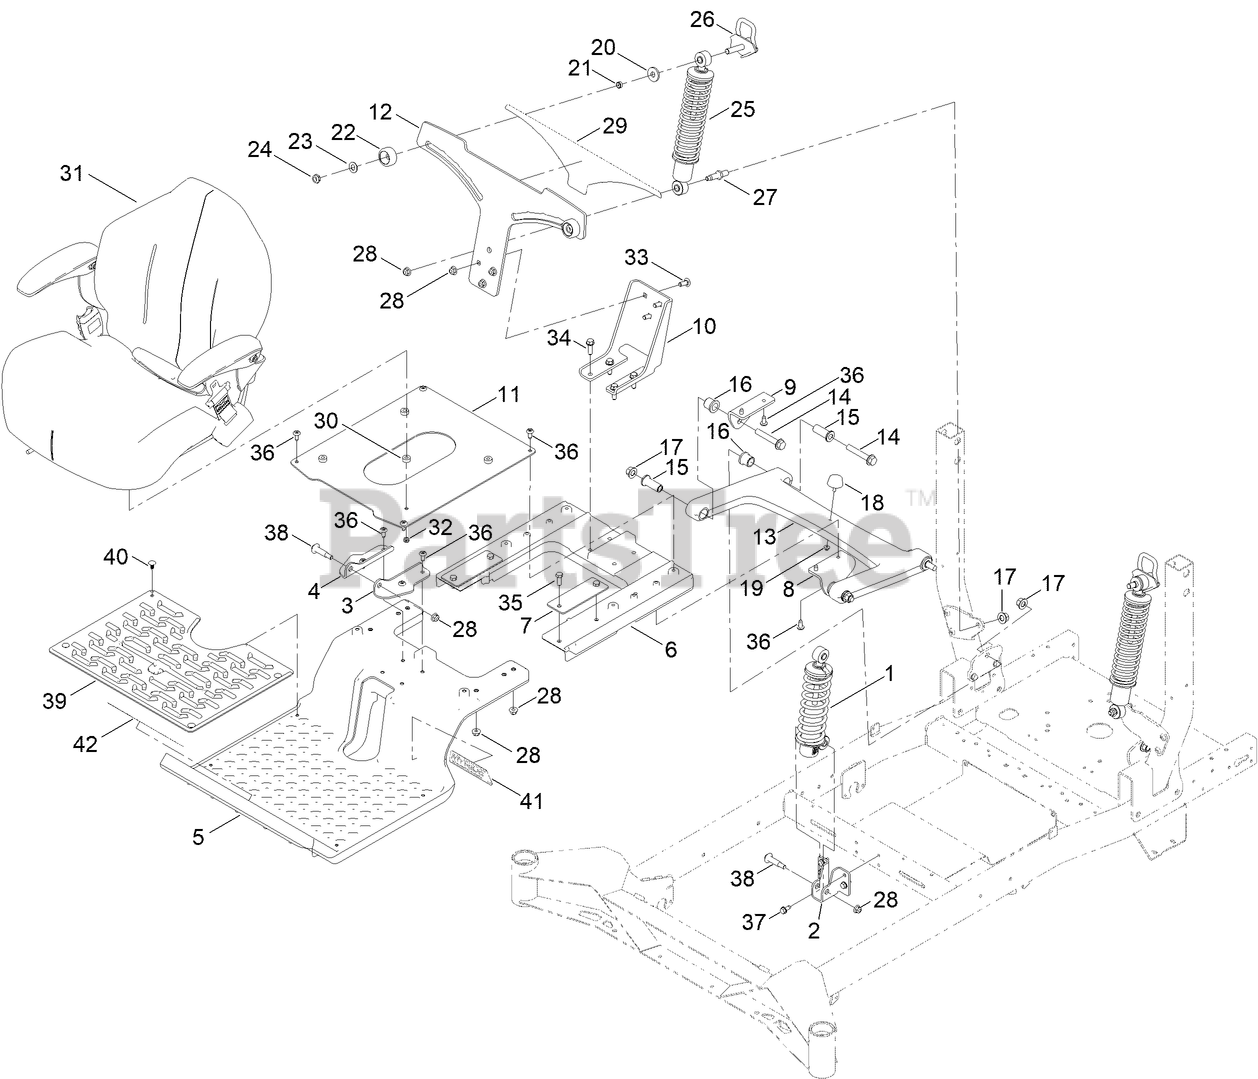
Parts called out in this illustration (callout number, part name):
1	SHOCK/SPRING ASM
2	BRACKET-MOUNT DAMPER, LOWER
3	BRACKET-SHOCK MOUNT, UPPER LH
4	BRACKET-SHOCK MOUNT, UPPER RH
5	SUBFRAME-FRONT
6	SUBFRAME-REAR
7	PLATE-BACKER
8	BRACKET-TRAILING ARM, LH
9	BRACKET-TRAILING ARM, RH
10	BRACKET-MOUNT, LOWER
11	PLATE-SEAT, MYRIDE
12	PLATE-MOUNTING,ADJ SHOCK
13	TRAILING ARM
14	SCREW-HF
15	SPACER-PIVOT
16	BUSHING-FLANGE
17	NUT-LOCK
18	BUMPER
19	NUT-HF
20	WASHER-PLASTIC
21	BEARING-SLEEVE
22	KNOB-LOCK, CAM
23	WASHER-ADJUSTING
24	NUT-HEX
25	SHOCK/SPRING ASM
26	CAM LOCK ASM
27	BOLT-SHOULDER
28	NUT-HF, NI
29	DECAL-MYRIDE
30	SPACER
31	SEAT ASM
32	NUT-LOCK, NI
33	SCREW-CARR
34	SCREW-THD
35	SCREW-HH
37	SCREW-HWHTF
38	BOLT-SHOULDER, HWH
39	FLOOR MAT
40	PLUG-PLASTIC
41	DECAL-MYRIDE
42	DECAL-MYRIDE
